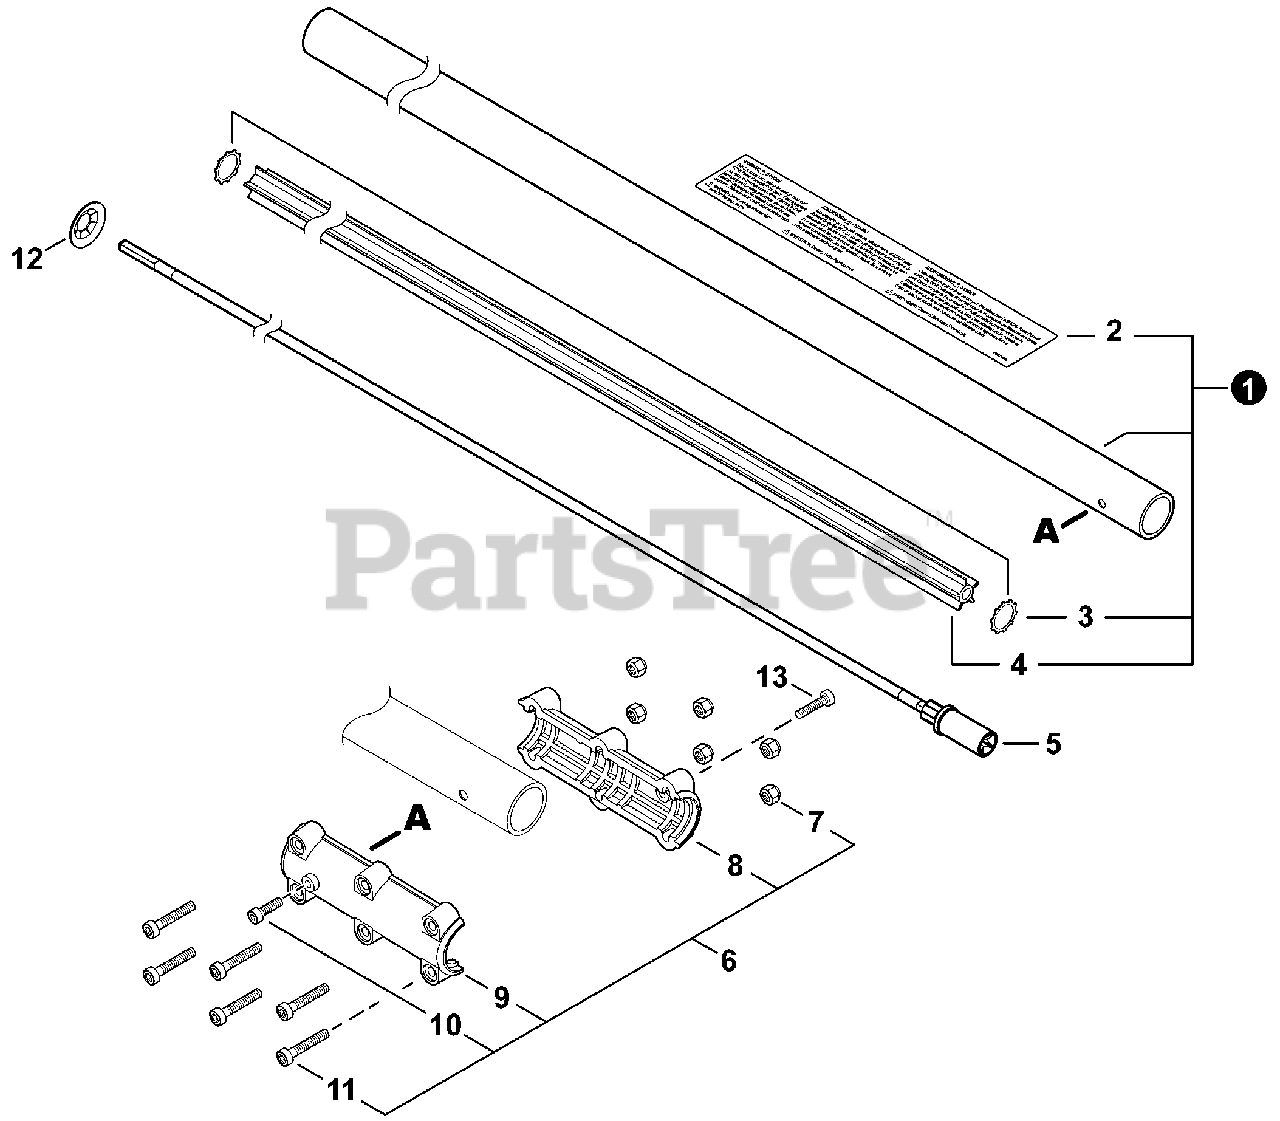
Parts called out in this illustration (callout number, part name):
1	MAIN PIPE ASSY
2	LABEL, CAUTION
4	LINER - FLEXIBLE
5	DRIVESHAFT - FLEXIBLE
6	COUPLER KIT
7	NUT, LOCK M5
8	COLLAR, MAIN PIPE - NUT SIDE
9	COLLAR, MAIN PIPE - BOLT SIDE
10	BOLT, TORX 5×12
11	BOLT, TORX 5×30
12	STOPPER, SHAFT
13	BOLT, TORX 5×12
